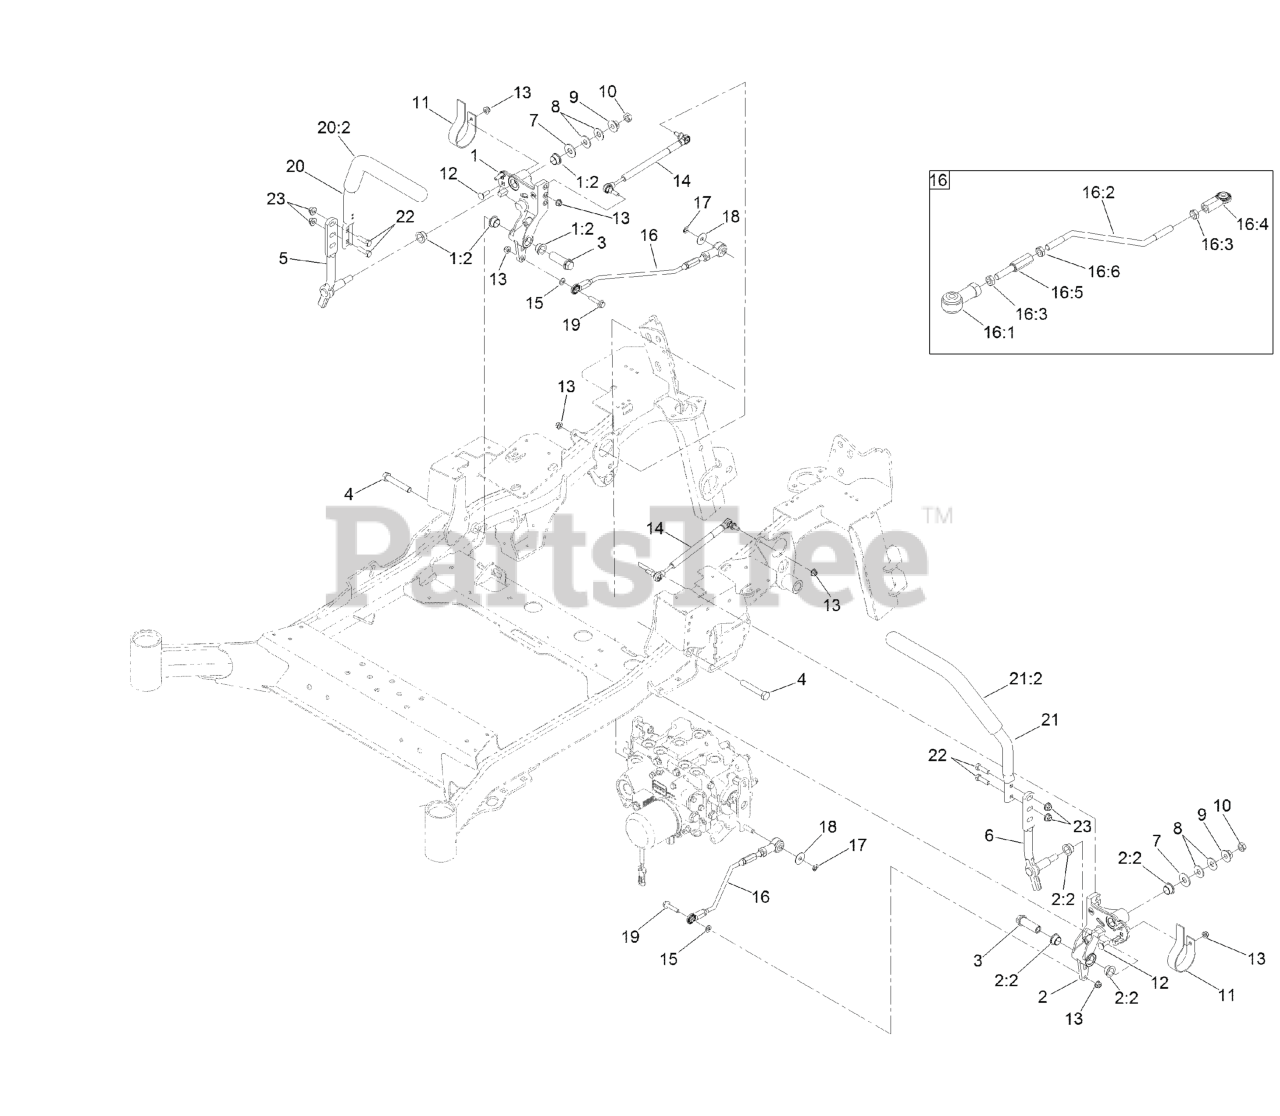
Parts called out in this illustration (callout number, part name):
1	RH MOTION CONTROL AND BUSHING ASM
1:2	BUSHING-FLANGE
2	LH MOTION CONTROL AND BUSHING ASM
2:2	BUSHING-FLANGE
3	HUB-THREADED
4	SCREW-HH
5	LEVER-CONTROL MOTION, RH
6	LEVER-CONTROL MOTION, LH
7	WASHER-FLAT
8	WASHER-SPRING
10	NUT-JAM
11	SPRING-LEAF
12	BOLT-CARR
13	NUT-HF, NI
14	DAMPER-CONTROL, MOTION
15	WASHER-PLAIN
16	FRONT LINKAGE ROD ASM
16:1	END-ROD, ISOLATED
16:2	ROD-LINKAGE, REAR
16:3	NUT-HJ
16:4	JOINT-BALL, END
16:5	ROD-ADJUSTMENT
16:6	NUT-HEX JAM, LH
17	RING-RETAINING
18	WASHER-PLAIN
19	SCREW-HHF
20	RH STEERING HANDLE ASM
20:2	GRIP-LEVER, CONTROL
21	LH STEERING HANDLE ASM
21:2	GRIP-LEVER, CONTROL
22	SCREW-HH
23	NUT-HF, NI
